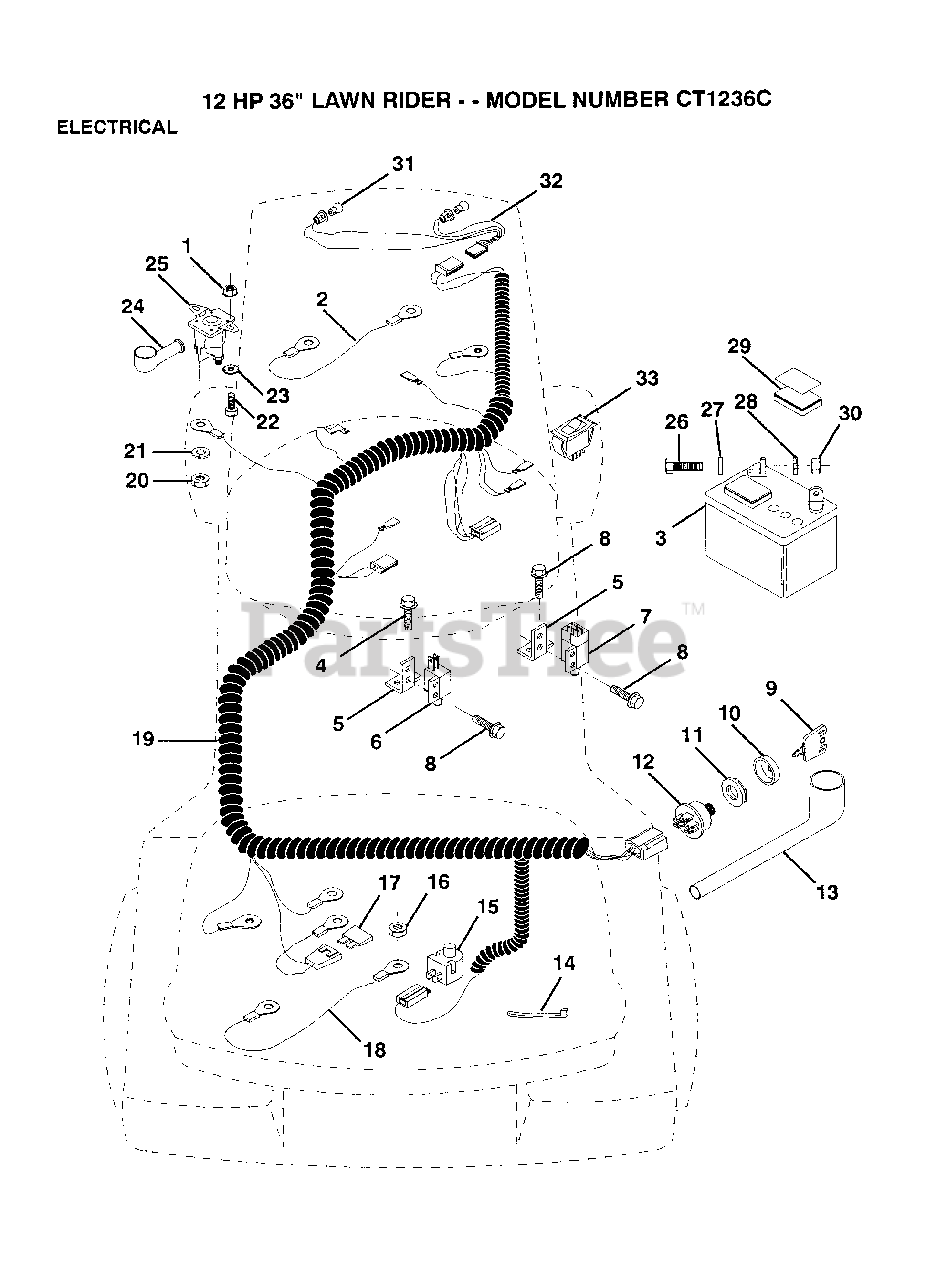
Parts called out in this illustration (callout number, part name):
1	NUT
2	CABLE ASM.
4	SCREW
5	BRACKET LT
6	SWITCH-INTER. GT
7	SWITCH INTERLOCKT
8	SCREW
9	KEY
11	NUT IGNITION
13	COVER IGNITION SW
14	WIRE TIE
15	SWITCH SEAT
17	FUSE HYT
18	CABLE ASSY
20	NUT
22	BOLT
26	BOLT LT
27	WASHER
28	LOCKWASHER
29	"CAP,BATTERY "
33	SWITCH LT
